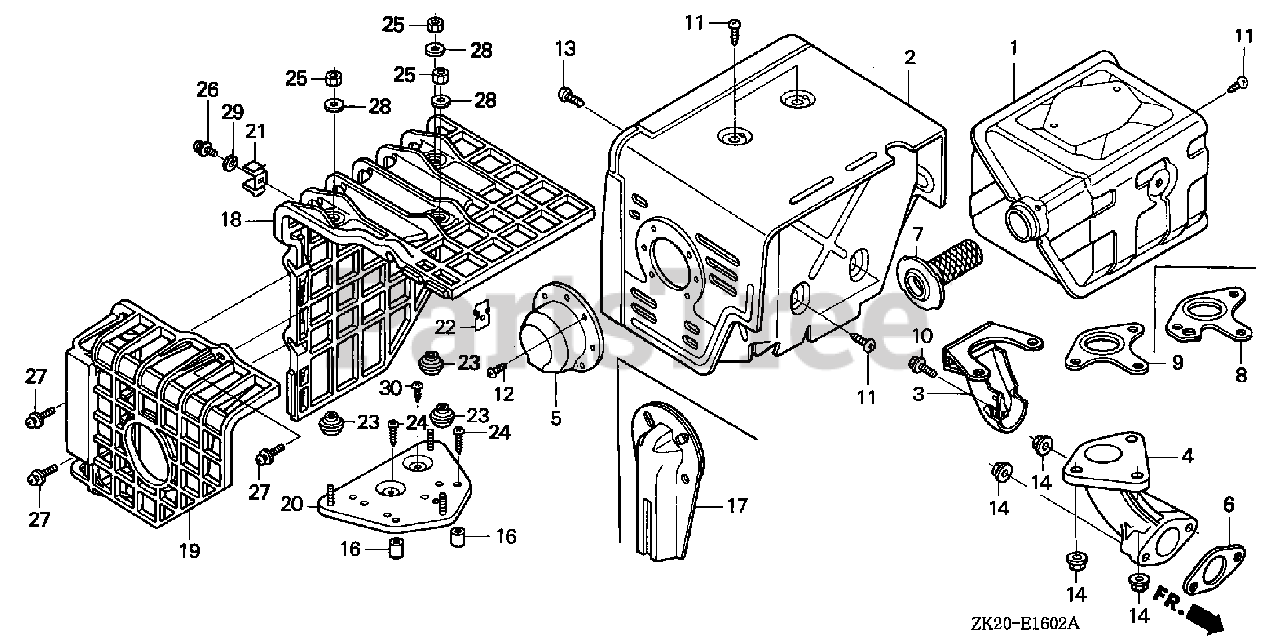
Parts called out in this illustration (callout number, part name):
1	MUFFLER (100DB)
2	PROTECTOR, MUFFLER
4	PIPE, EX.
6	GASKET, EX. PIPE
6	GASKET, EX. PIPE (WACKER)
7	ARRESTER, SPARK
8	GASKET, MUFFLER (ARRESTER)
11	SCREW, TAPPING (5X8)
13	SCREW, TAPPING (6X10)
14	NUT, FLANGE (8MM)
